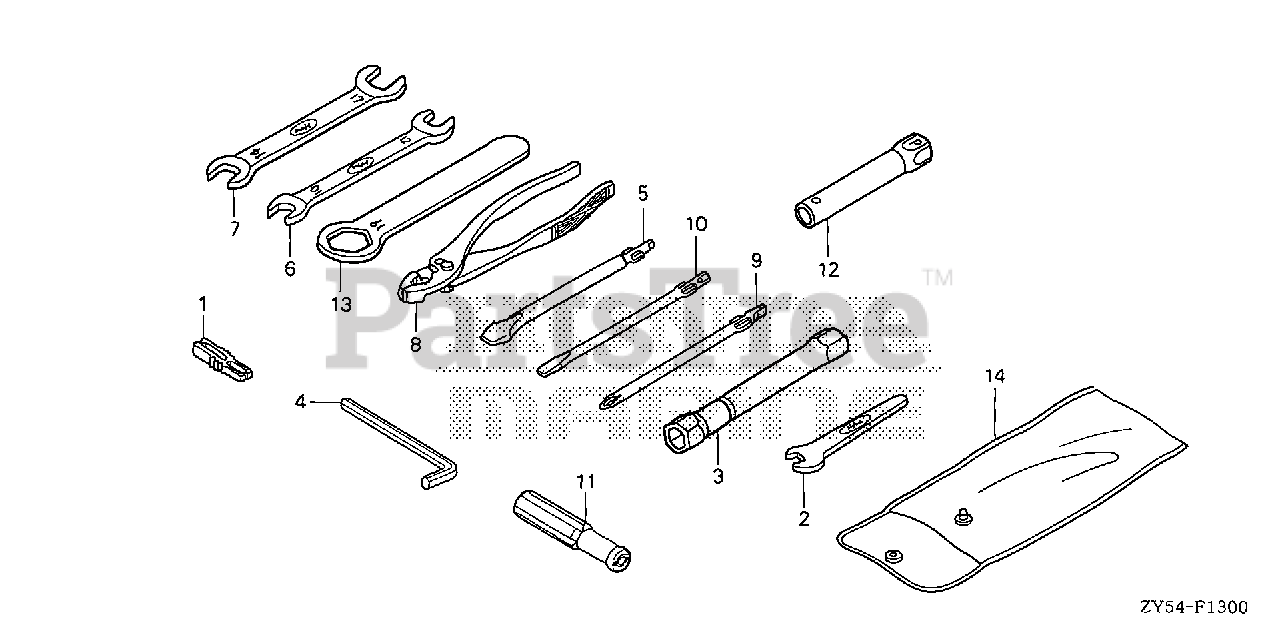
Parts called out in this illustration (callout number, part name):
1	PULLER, MINI FUSE (SUMITOMO)
2	WRENCH (8MM) (OPEN END) (NOT AVAILABLE)
3	WRENCH, PLUG
4	WRENCH, HEX. (6MM)
5	SCREWDRIVER, CHECK BOLT
6	WRENCH (10X12) (OPEN END)
7	WRENCH (14X17) (OPEN END)
8	PLIERS (135) (KOWA)
8	PLIERS (135) (RIKEN)
9	SCREWDRIVER 1, PHILLIPS (NO.2)
10	SCREWDRIVER 3, STRAIGHT SLOT (NO. 2)
11	GRIP, SCREW DRIVER
12	WRENCH, BOX (P16X17)
13	WRENCH, EYE (19MM)
14	BAG, TOOL (230MM)
